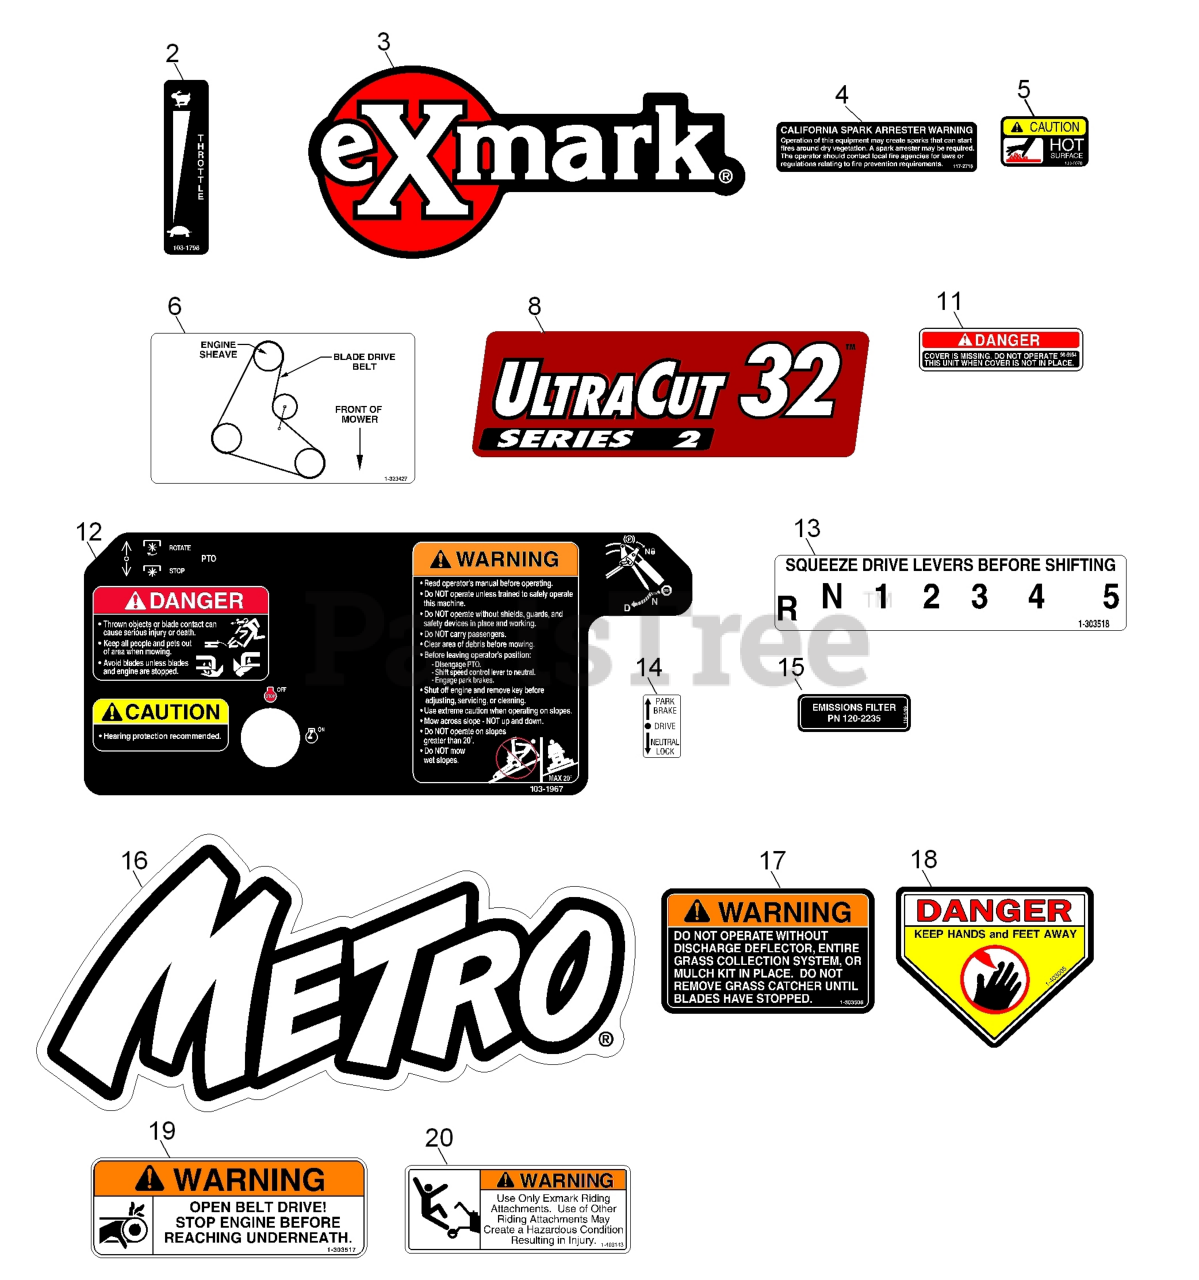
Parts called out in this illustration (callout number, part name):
2	DECAL,THROTTLE ONLY
3	DECAL,EXMARK LOGO
4	DECAL-ARRESTER, SPARK
5	DECAL-CAUTION
6	DECAL,BELT ROUTING 32/36
8	DECAL-ULTRACUT 32 SERIES
11	DECAL-COVER, MISSING
12	DECAL,CONSOLE
13	DECAL,SHIFTER
14	DECAL,NEUTRAL/BRAKE
15	DECAL-FILTER, EMISSIONS
16	DECAL,METRO MODEL
17	DECAL-WARNING, DISCHARGE
18	DECAL-DANGER
19	DECAL,BELT DRIVE
20	DECAL,SULKY WARNING
